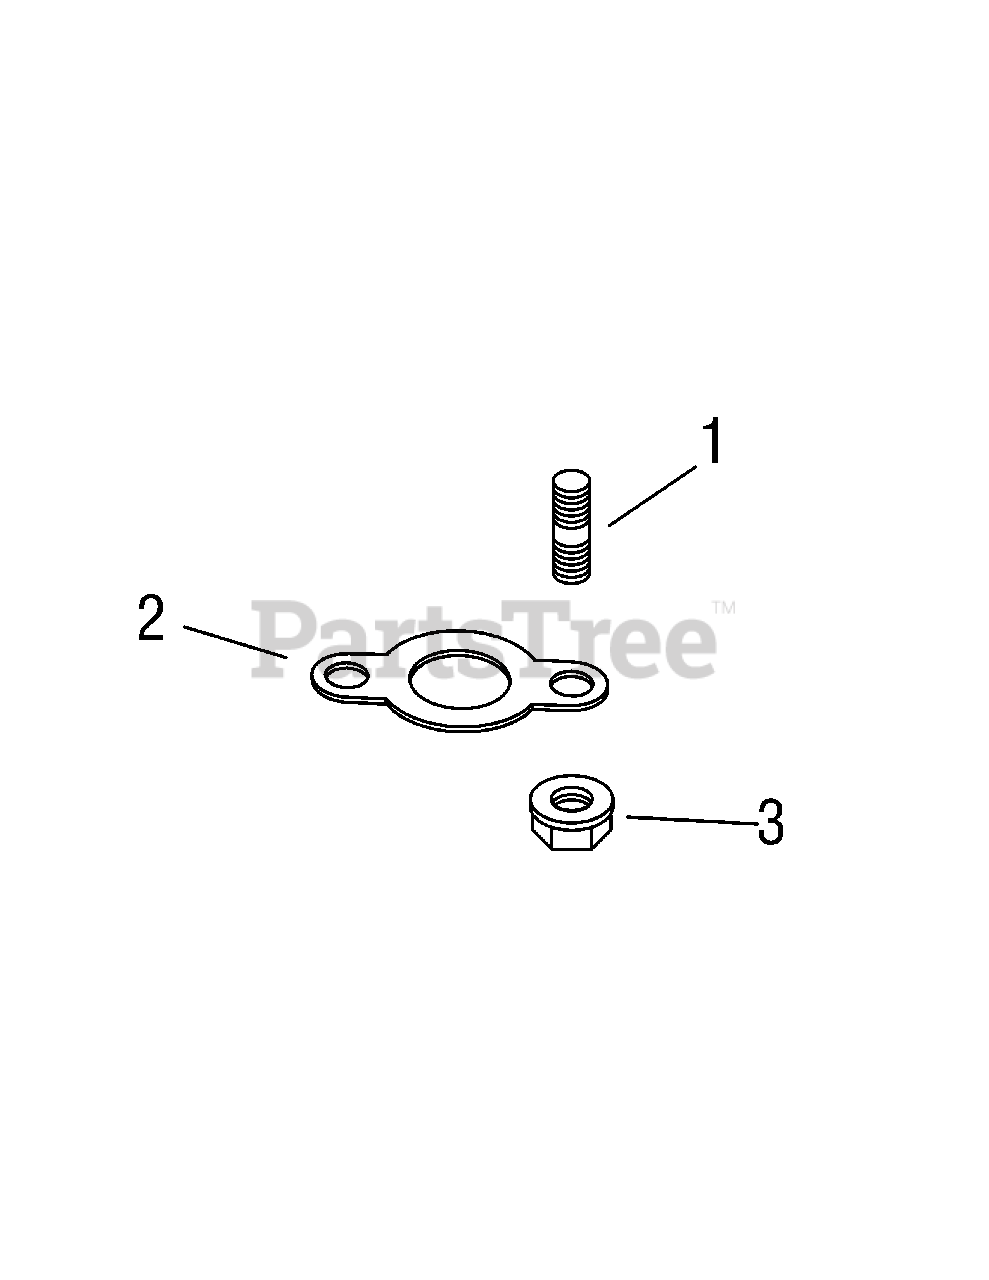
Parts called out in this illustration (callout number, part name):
1	Stud, M8 x 1.25 x 33
2	Exhaust Manifold Gasket
3	Hex Flange Nut, M8 x 1.25
